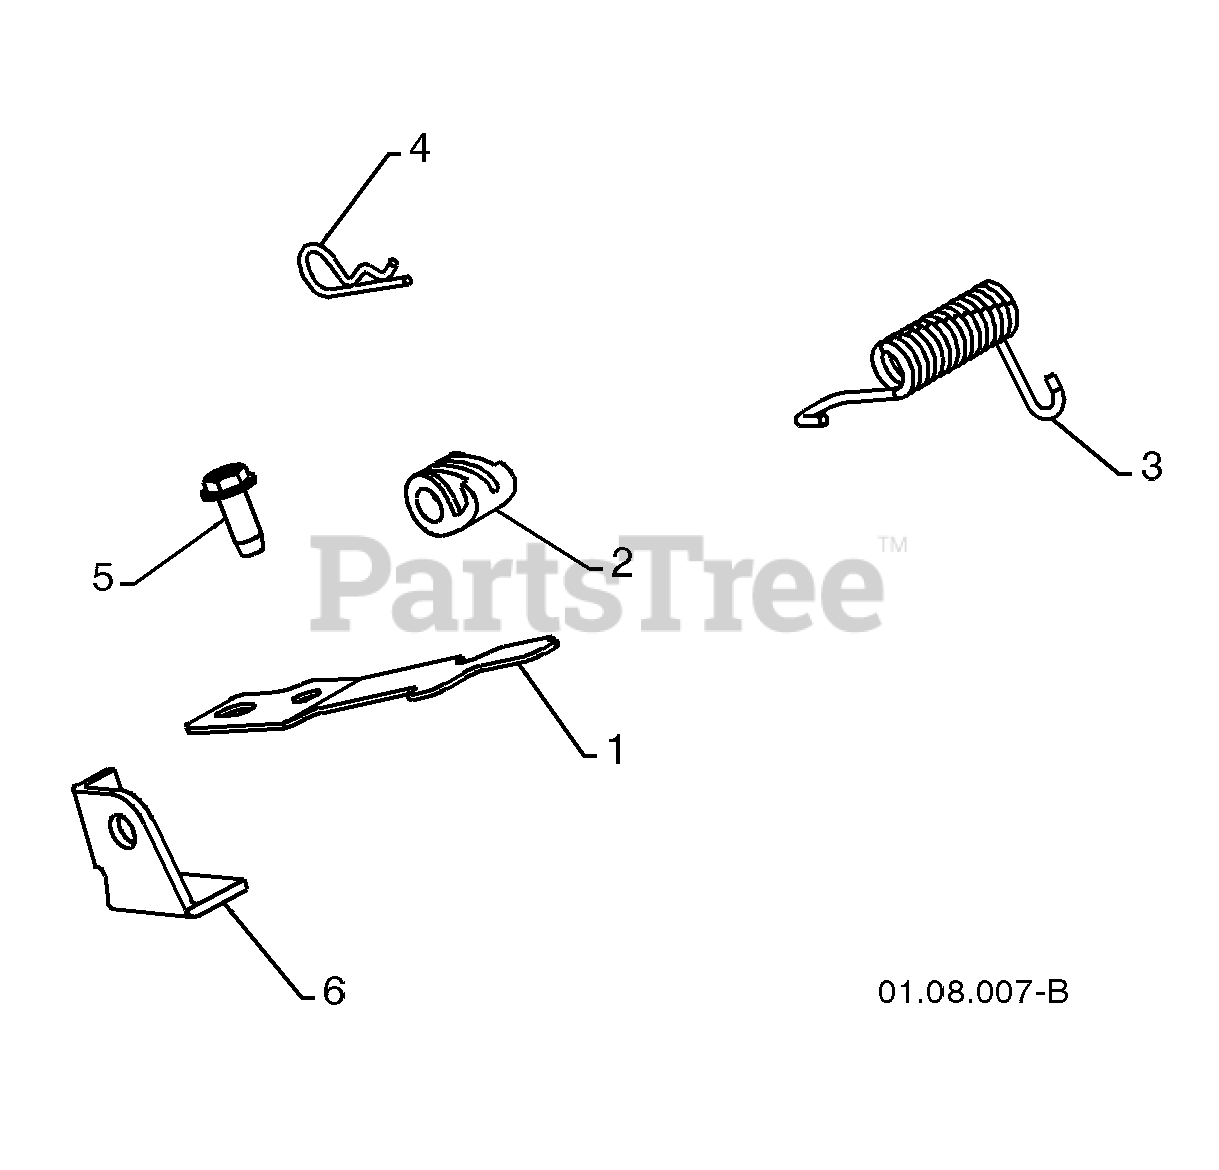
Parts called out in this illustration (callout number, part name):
1	INTERLOCK SPRING
2	INTERLOCK CAM
3	TORSION SPRING
5	SCREW 1/4-20 X .625
6	INTERLOCK STOP
